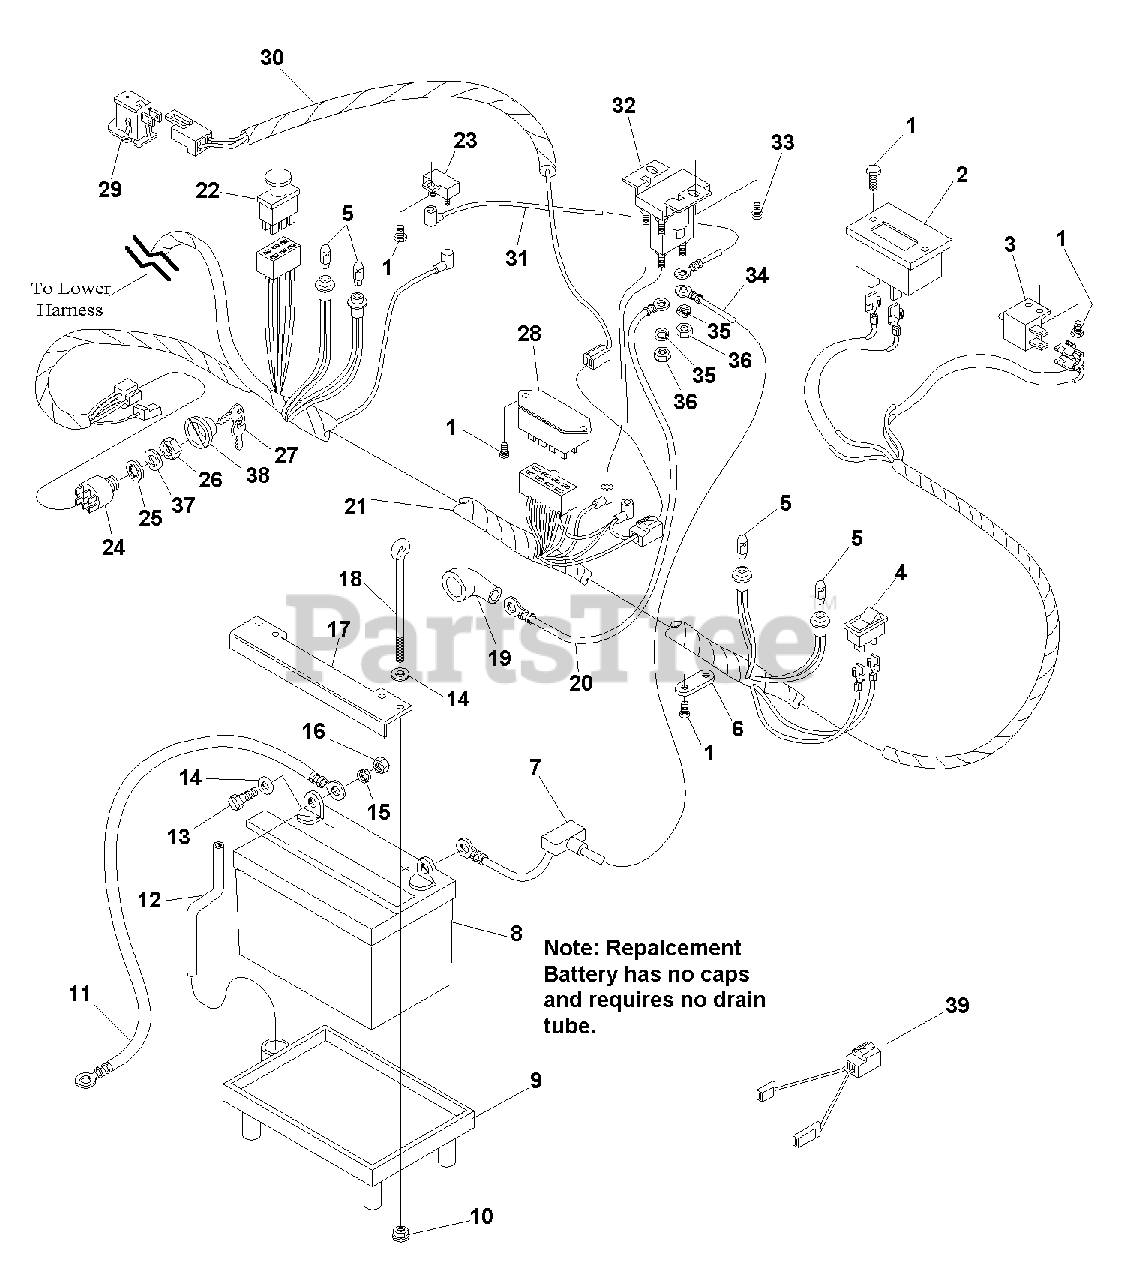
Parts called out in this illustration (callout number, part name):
1	CAPSCREW, Plastite, #8-16 x 1/2
3	SWITCH, Neutral
4	SWITCH, Headlight
5	BULB, Indicator Light
6	STRAP, Wire Retainer
7	BOOT, Insulator
9	TRAY, Battery
10	NUT, Plastic, 1/4-20
11	CABLE, Battery to Ground
12	HOSE, Battery, Drain
13	CAPSCREW, Hex Head, 1/4-20 x 3/4
14	WASHER, Plain, 1/4
15	LOCKWASHER, 1/4
16	NUT, Hex, 1/4-20 UNC
17	HOLD DOWN, Battery
18	ROD, Battery Hold Down
19	COVER, Terminal
20	CABLE, Solenoid to Starter
21	WIRE HARNESS, Main
22	SWITCH, PTO Electric Clutch
23	CIRCUIT BREAKER
24	IGNITION SWITCH, 6-Pin, Steel Body (Includes Ref. Nos. 25, 26, 27, 37 & 38)
25	LOCKWASHER, Internal
26	NUT, Hex, Flange
27	KEY, Ignition, Set of 2
29	SWITCH, Clutch Brake Pedal
30	WIRE ASSEMBLY
31	WIRE ASSEMBLY
32	SOLENOID
33	CAPSCREW, Hex Washer Head, Plastite, 1/4-20 x 1/2
34	CABLE, Battery to Solenoid
35	LOCKWASHER, 5/16
36	NUT, Hex, 5/16-24
37	WASHER, 5/8 x 1
38	COVER, Ignition Switch
39	WIRE ASSEMBLY, Kohler to Wire Harness
